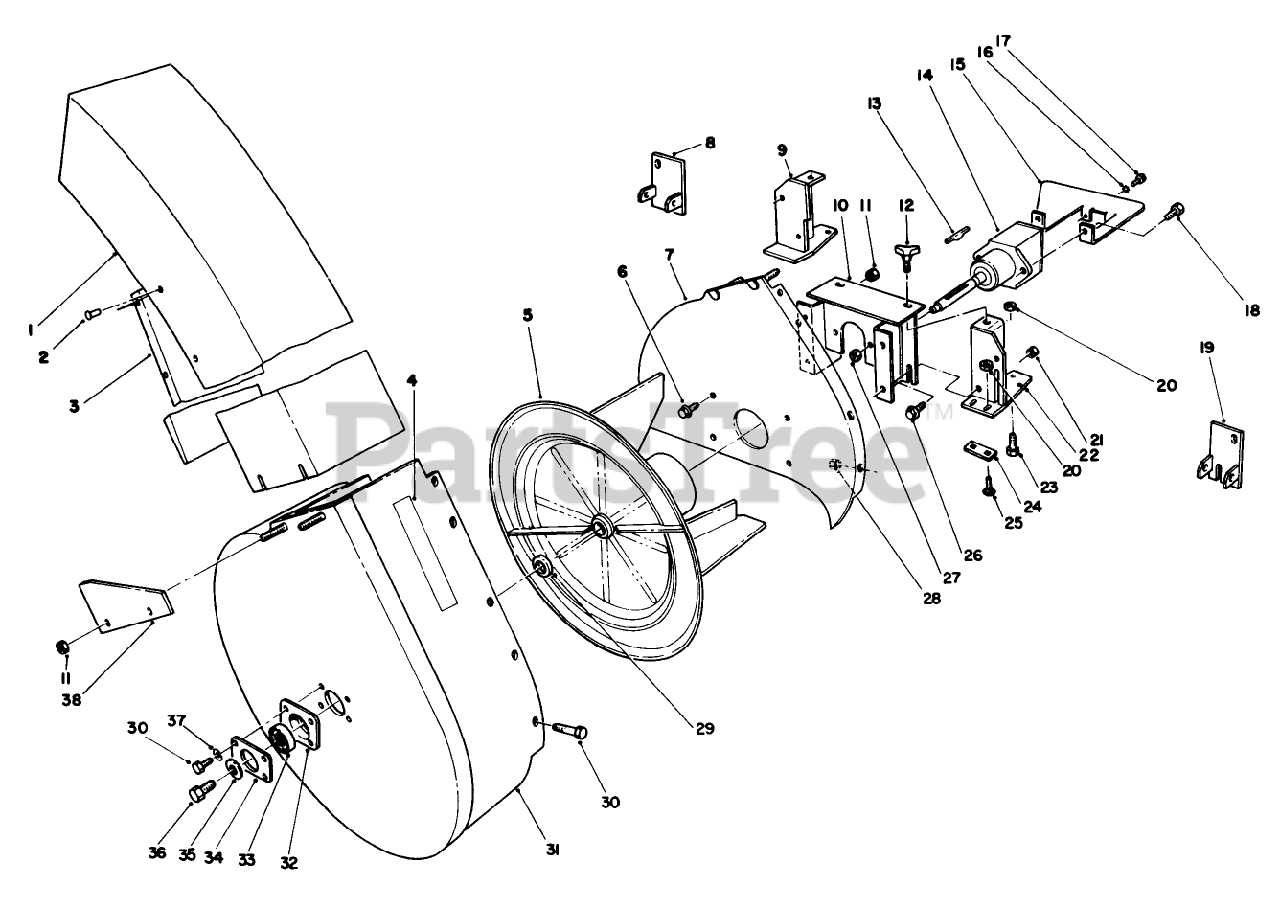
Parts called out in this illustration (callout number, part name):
1	Chute Assembly (Incl. Ref. #2 & 3)
3	Deflector
4	Decal-Waming
5	Impeller
6	SCREW-HHF
7	Mounting Plate
8	Bracket-Deflector L.H.
9	LH BRACKET ASM
10	Blower Mount
11	NUT-LOCK, NI
14	Asm-Gear Box
15	Cover-Gear Box
16	WASHER-LOCK, EXT
18	SCREW-HH
19	Bracket-Deflector R.H.
20	NUT-LOCK, CONE
21	NUT-JAM
22	RH BRACKET ASM
23	SCREW-HH
24	Plate-Bracket
25	BOLT-CARR
26	SCREW-HHF
27	NUT-LOCK, NI
28	NUT-LOCK, NI
29	SPACER-BEARING
30	SCREW-HH
31	BLOWER HOUSING ASM
32	CUP-BEARING
33	BEARING-BALL
34	Cover-Plate
35	SPACER
36	SCREW-HH, LOCK
37	WASHER-LOCK
38	Bracket
